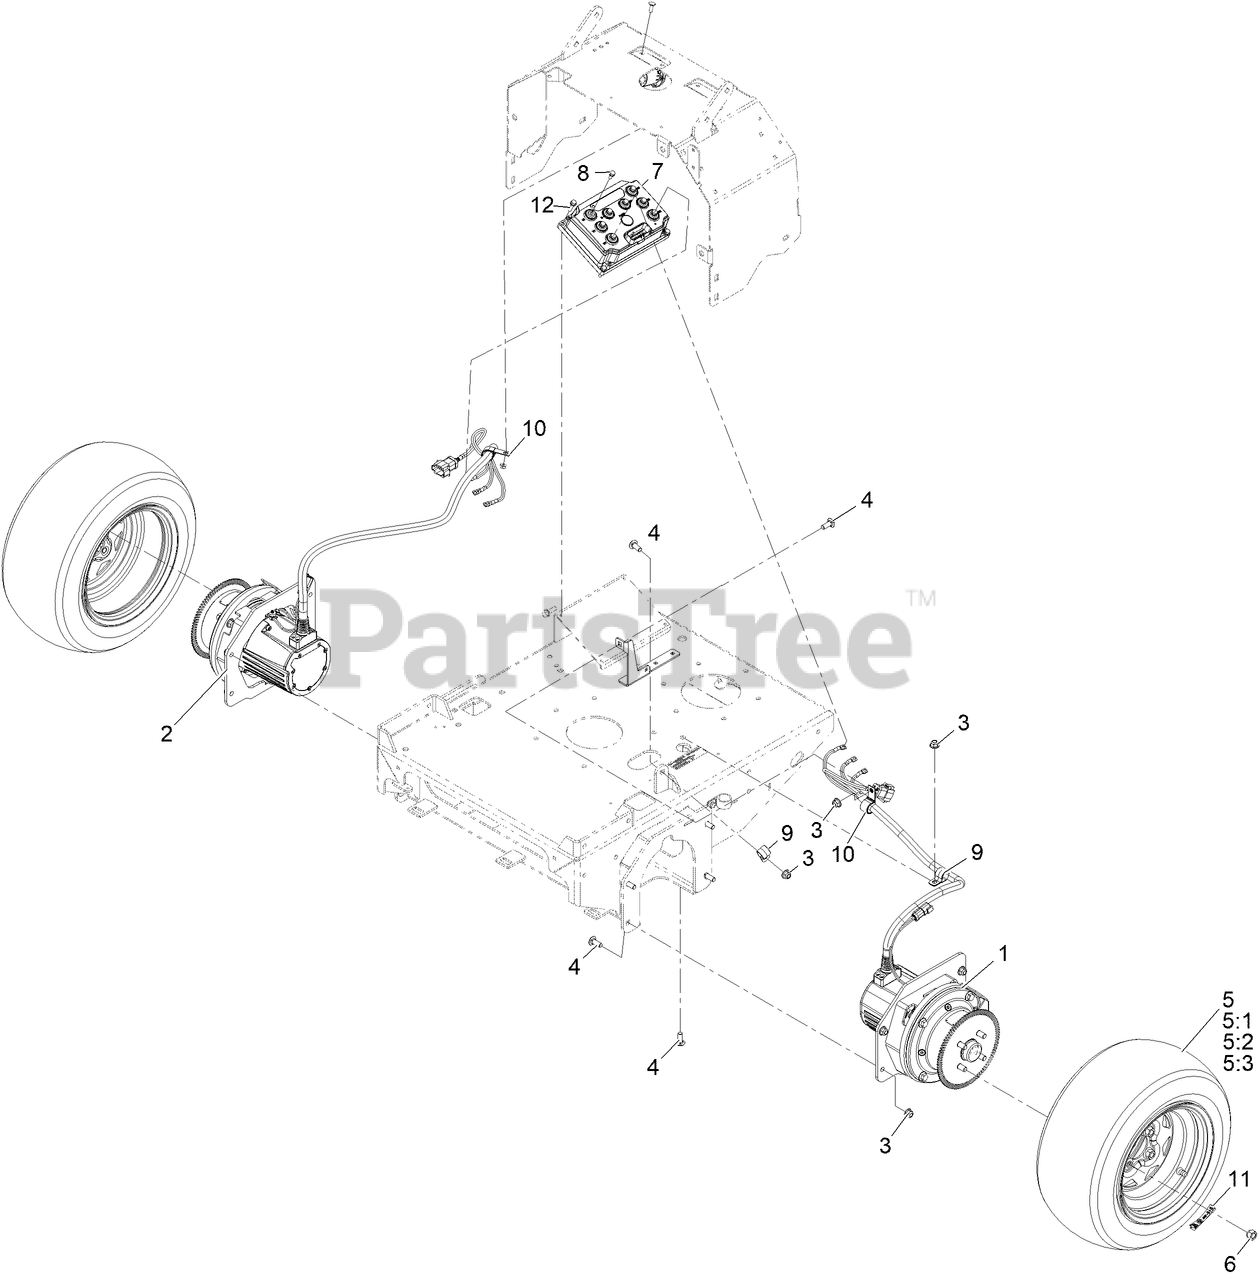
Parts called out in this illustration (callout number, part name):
1	LH Motor Sub ASM
2	RH Motor Sub ASM
3	NUT-HF, NI
4	SCREW-CARR
5	TIRE ASM
5:1	Rim-10 In
5:2	TIRE, 18X 8.50-10
5:3	Stem-Valve
6	NUT-WHEEL
7	INV/CTRLR-48V,DUAL 94ARMS
8	SCREW-SEMS
9	CLAMP-R
10	CLIP-OPEN J, COATED
11	DECAL-TORQUE,WHEEL LUG
12	SCREW-HWHTF
